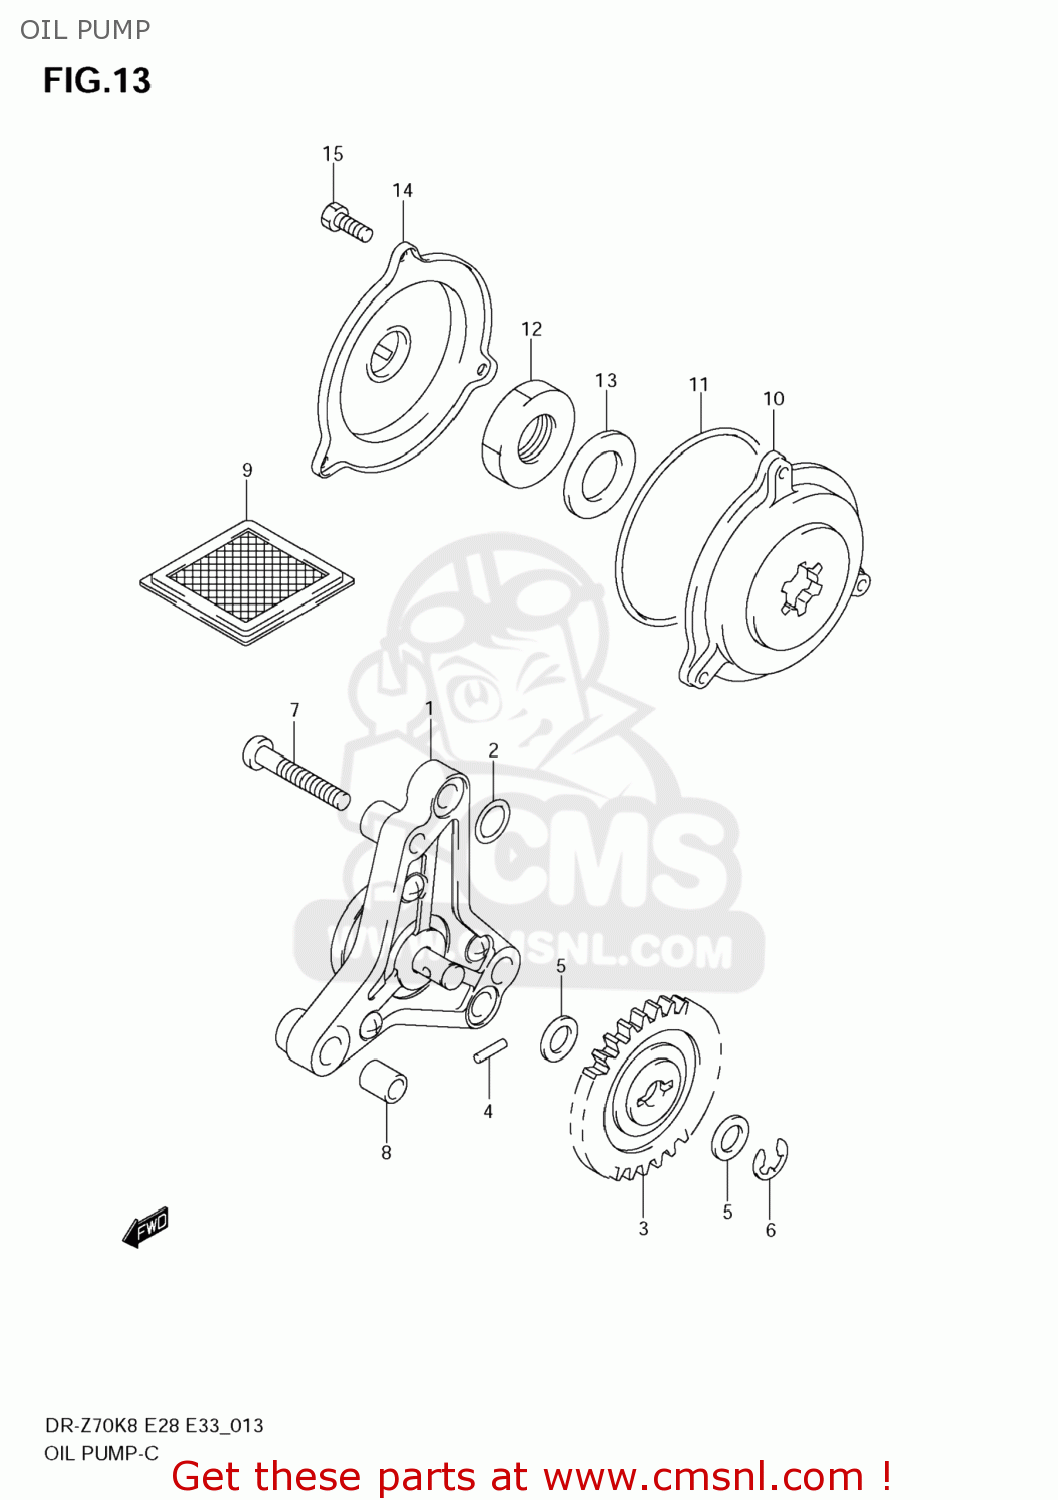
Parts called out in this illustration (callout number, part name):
1	PUMP ASSY,ENGINE OIL
2	O RING(D:1.9,ID:9.8)
3	GEAR,OIL PUMP DRIVEN (N
4	PIN(2.5X11.8)
5	SHIM(8.8X14X1)
6	E RING
7	SCREW
8	PIN
9	STRAINER,ENGINE OIL
10	CASE,ENGINE OIL FILTER
11	O RING(D:2.4,ID:60.5)
12	NUT
13	WASHER
14	COVER,ENGINE OIL FILTER
15	BOLT(5X10)
